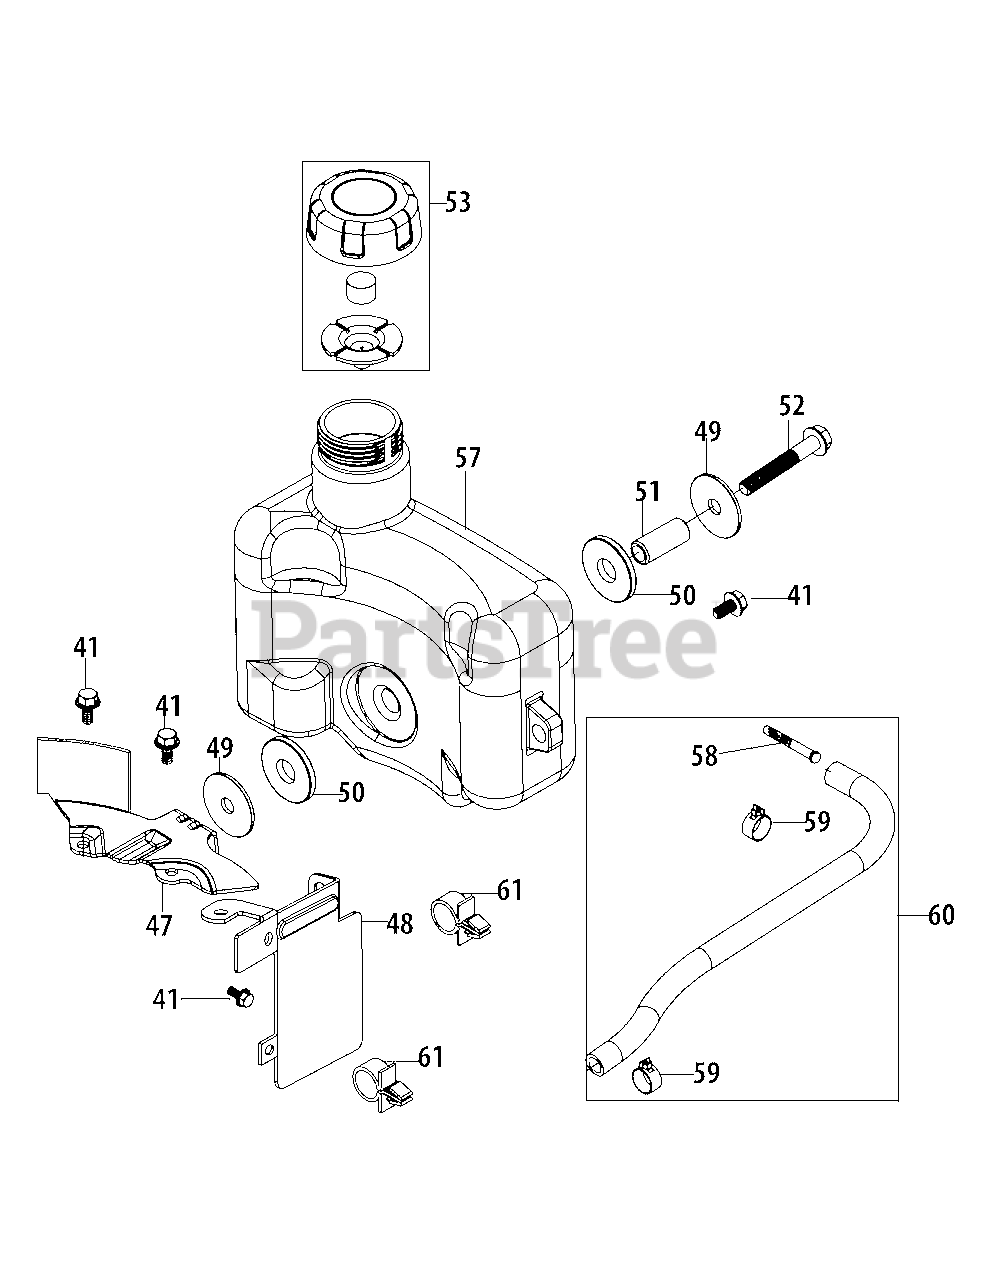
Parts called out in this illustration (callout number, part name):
41	Bolt M6X14 Multi-Purpose
47	Fuel Tank Bottom Bracket
48	Fuel Tank / Label Bracket
49	Fuel Tank Washer
50	Rubber Bushing
51	Fuel Tank Bushing
52	Bolt M8X50 Fuel Tank
53	Fuel Cap Assembly
57	Fuel Tank Assembly
58	Fuel Filter
59	Fuel Hose Clamp
60	Fuel Hose Kit
61	Plastic Support Clamp
